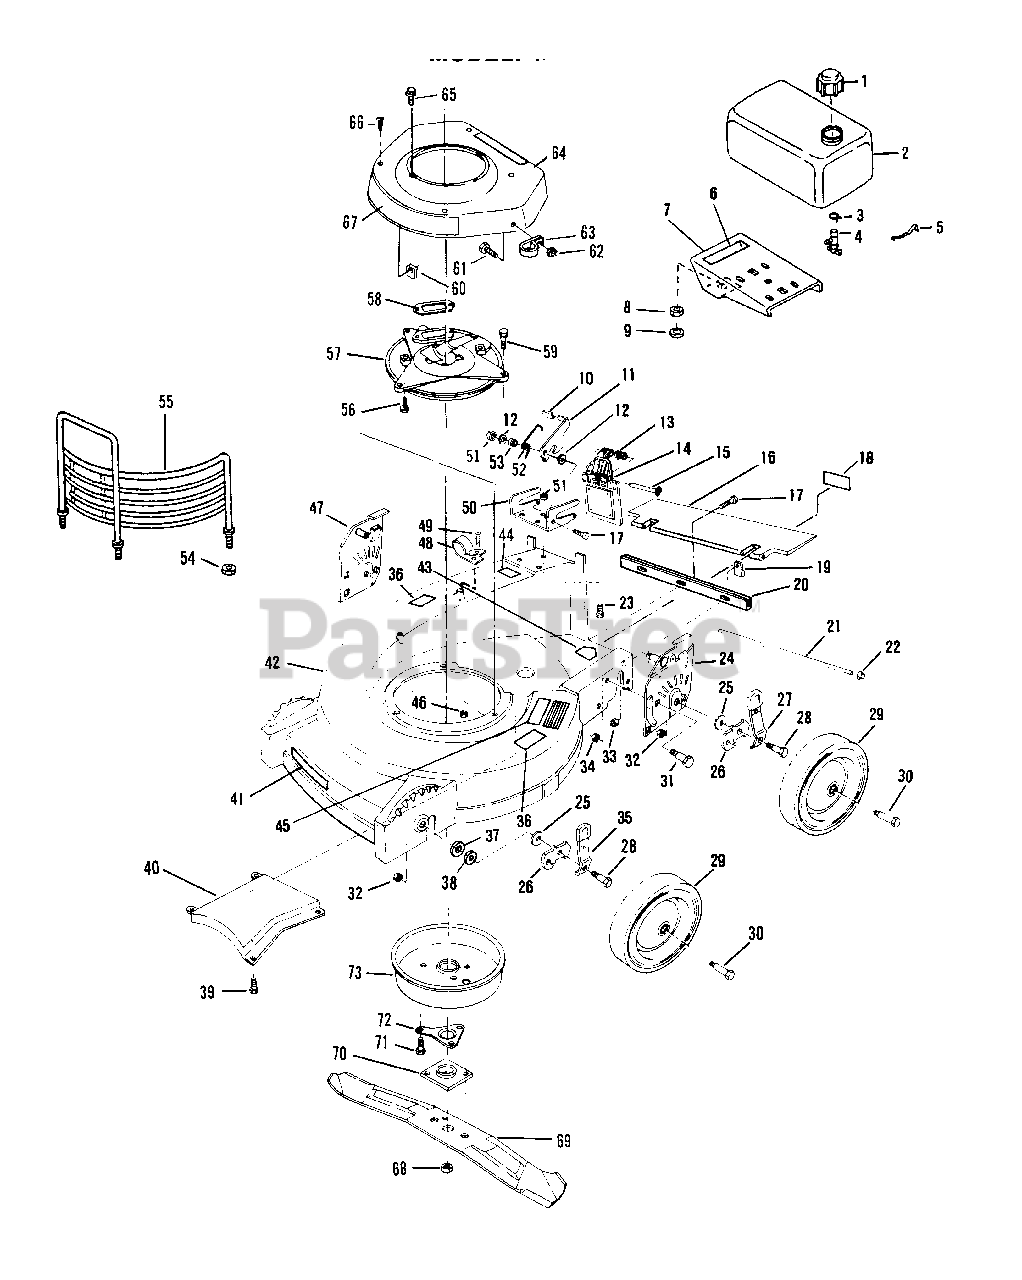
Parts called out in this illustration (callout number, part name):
1	Fuel Cap
2	Fuel Tank
3	Clamp
4	Shut-Off Valve and Screen
5	Spring-Fuel Tank Mounting
6	Decal-Fuel Mixture
7	Bracket-Fuel Tank
8	Nut-Tank Mounting
9	Washer-Tank Mounting
10	Knob-Latch
11	Latch-Bag
12	Washer-Latch Spacer and Latch Spring
13	Spring
14	Door
15	Rod
16	Trailing Shield
17	Screw-Latch Mounting and Trailing Shield
18	Decal-Caution
19	Clamp-Rod
20	Bracket-Bag Support
21	Rod-Trailing Shield
22	Nut-Rod
23	Screw
24	Handle Bracket Assembly-L.H.
25	Washer-Height Adjust
26	Bracket-Wheel Height Adjust
27	Knob and Spring Assembly-Rear
28	Bolt-Shoulder
29	Wheel and Tire Assembly
30	Bolt-Wheel
31	Screw-Handle Bracket to Housing
32	Nut-Wheel Bracket to Housing
33	Nut
34	Nut-Handle Bracket to Housing
35	Knob and Spring Assembly-Front
36	Decal-Cutting Height
37	Washer-Shim
38	Washer-Shim
39	Screw
40	Baffle
41	Decal-Headliner
42	Housing-20"
43	Decal-Blade Contact
44	Decal-Commercial Mower
45	Decal-Commercial Safety Warning
46	Nut
47	Handle Bracket Assembly-R.H.
48	Clamp-Cable to Housing
49	Screw-Clamp to Housing
50	Hinge Plate
51	Nut
52	Spring-Latch
53	Stepped Spacer
54	Nut-Guard Mounting
55	Engine Guard
56	Screw-Muffler Plate to Block
57	Plate-Muffler
58	Gasket-Exhaust
59	Screw-Muffler Plate to Housing
60	Retainer-Applique
61	Screw
62	Nut
63	Clamp
64	Shroud and Nut Assembly
65	Screw-Starter Mounting
66	Screw-Shroud Mounting
67	Applique-Shroud
68	Nut-Blade
69	Blade-20"
70	Collar and Plate Assembly
71	Screw-Muffler Cover to Plate
72	Support-Crankshaft
73	Muffler Cover Assembly
